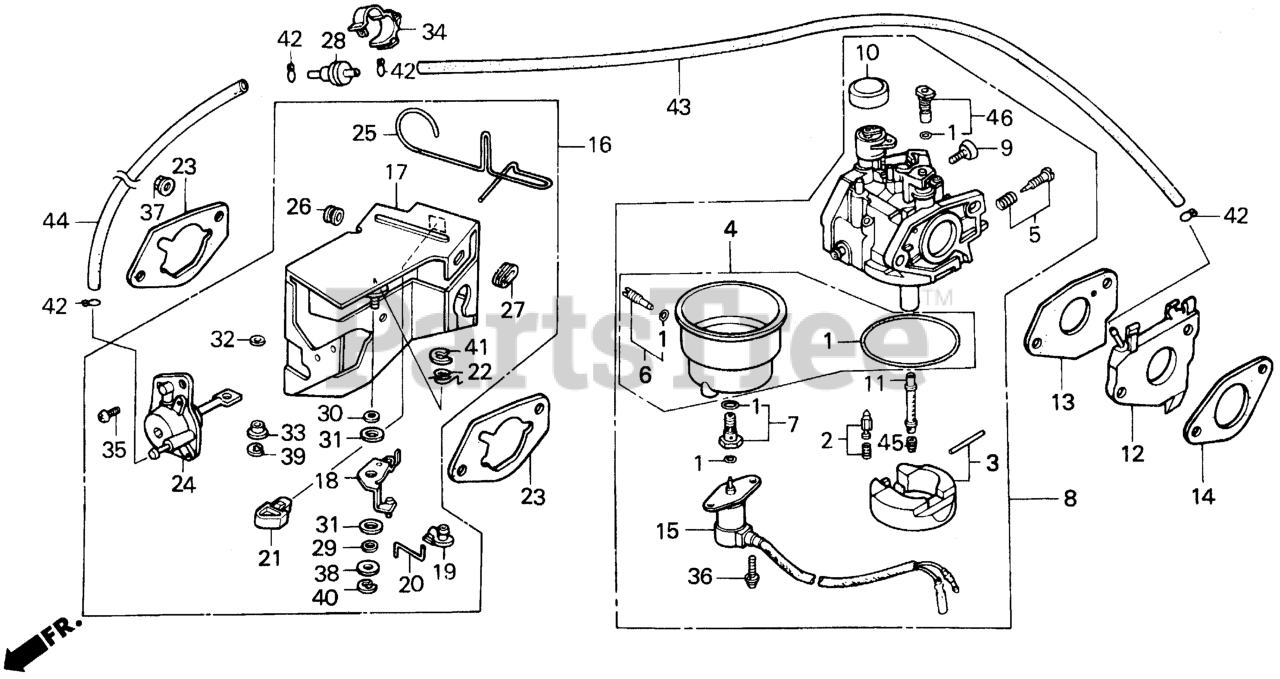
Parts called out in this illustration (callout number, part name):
1	GASKET SET
2	VALVE SET, FLOAT
3	FLOAT SET
4	CHAMBER SET, FLOAT
5	SCREW SET, PILOT (Honda Code 1441500). (CARBURETOR NO.)
6	SCREW SET, DRAIN (ADVENTURE GREEN) (CARBURETOR NO.)
7	SCREW SET
8	CARBURETOR ASSY. (BE37A B)
8	CARBURETOR ASSY. (BE37A C)
8	CARBURETOR ASSY. (BE37A D)
9	SCREW, THROTTLE STOP
10	CAP, CHOKE LEVER DUST
11	NOZZLE, MAIN (CARBURETOR NO.)
12	INSULATOR, CARBURETOR
13	GASKET, CARBURETOR
14	GASKET, INSULATOR
15	VALVE ASSY., SOLENOID
16	STAY ASSY., MANUAL CHOKE
17	STAY, SOLENOID (NA USE ALT:04103-ZE2-702)
17	STAY, SOLENOID
18	LEVER, CHOKE
19	JOINT, ROD
20	ROD, CHOKE
21	STOPPER, CHOKE ROD
22	SPRING, MANUAL CHOKE (NA USE ALT:04103-ZE2-702)
22	SPRING, MANUAL CHOKE
23	GASKET, AIR CLEANER
24	DIAPHRAGM ASSY. (NA USE ALT:04103-ZE2-702)
24	DIAPHRAGM ASSY.
25	ROD, CHOKE CONTROL
26	GROMMET, CHOKE ROD
27	GUIDE, CHOKE ROD
28	VALVE, DASHPOT CHECK
29	BUSH, ARM PIVOT
30	WASHER, CHOKE LEVER
31	SEAL, CHOKE LEVER
32	WASHER, THRUST (2.7X8)
33	COLLAR, LEVER
34	CLIP, WIRE HARNESS
35	SCREW, PAN (5X12)
36	SCREW-WASHER (5X12)
37	NUT, FLANGE (6MM)
38	WASHER, PLAIN (5MM)
39	E-RING (2MM)
40	E-RING (4MM)
41	E-RING (7MM)
42	CLIP, TUBE (B7)
43	BULK HOSE, VACUUM (3.5X8000) (3.5X130)
44	BULK HOSE, VACUUM (3.5X8000) (3.5X130)
45	JET, MAIN (#92) Use from Engine SN BB36B A.
45	JET, MAIN (#95)
45	JET, MAIN (#98)
46	JET SET, PILOT (#38)
